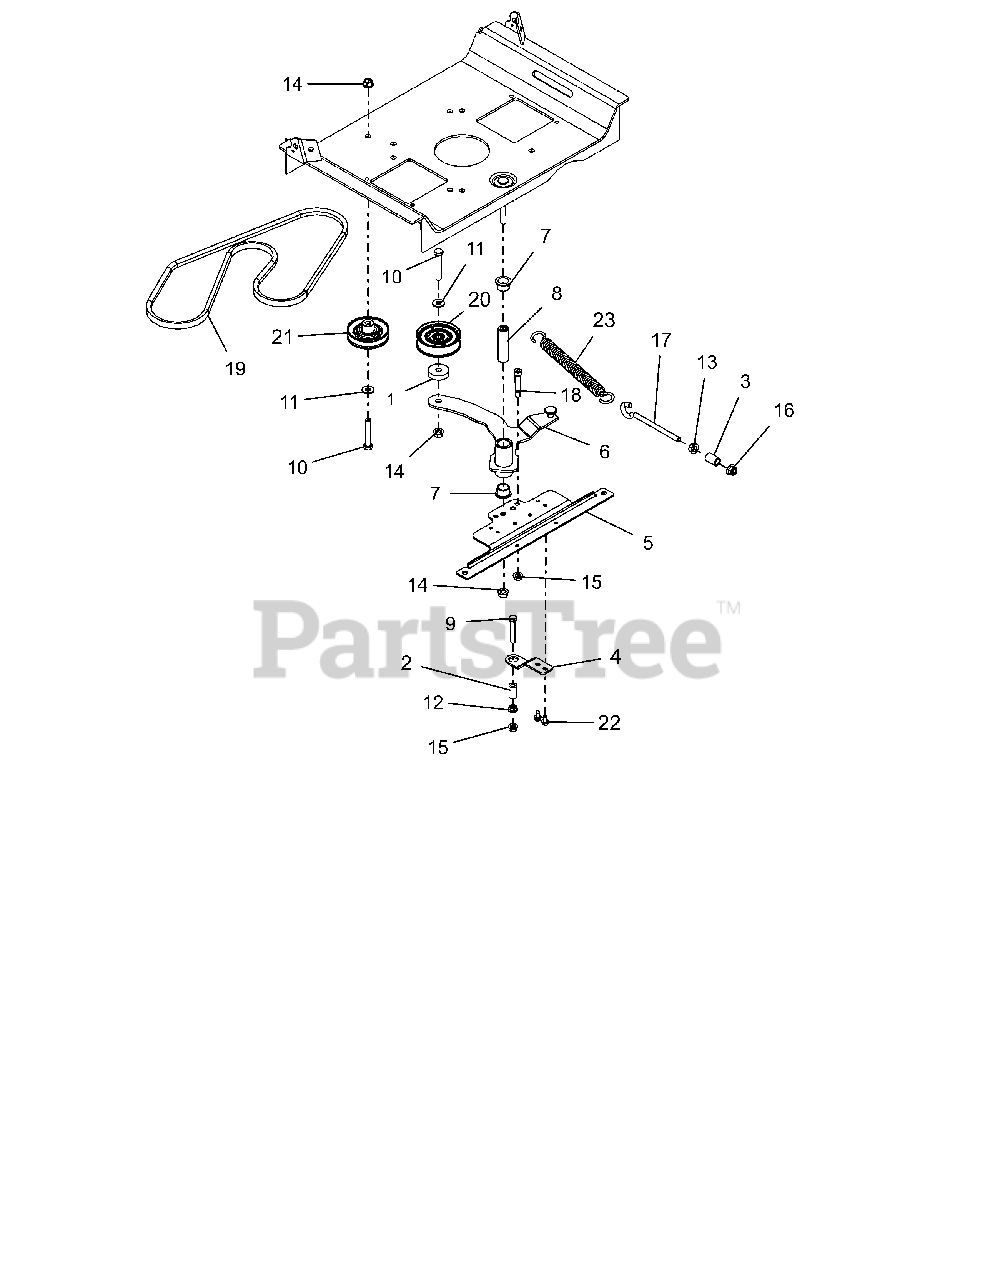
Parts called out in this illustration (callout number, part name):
1	SPACER, .39 X 1.50 X .380
2	SPACER, RUBBER 5/16 IDX1.0 LG
3	SPACER, .375X.625X.970 (PM)
4	BRKT, CLUTCH STOP
5	BRKT, DRIVE IDLER MOUNTING
6	WLDMT,GRD DRIVE IDLER ARM-LGR
7	BSHG-FLG 0.75X0.875X.625X1.125
8	BUSHING, SLEEVE .38X.750X2.78
9	@BLT-HEX .31-18X2.00 GR5 YWZC
10	@BLT-HEX .38-16X2.25 GR5 YWZC
11	@WSHR-FL-STL.38X.875X.083 YWZC
12	@NUT-SPNLK-FLG .312-18 YWZC
13	@NUT-SPNLK-FLG .375-16 YWZC
14	@NUT-LK-TOP-FLG .38-16 YWZC
15	@NUT-LK-TOP-FLG .31-18 YWZC
16	@NUT-LK-NYL-FLG .38-16 YWZC
17	BOLT,.38-16 X 4.25-.62 DIA EYE
18	BLT-SHLDR .38X1.5X.31-18 SLT Y
19	V-BELT, A-RAW EDGE
20	IDLER, FLAT - 3.05" X .75"
21	IDLER, V-3.000 OD
22	SCR-TAP .25-20X.50 HWH TR YWZ
23	SPRING, EXTENSION
